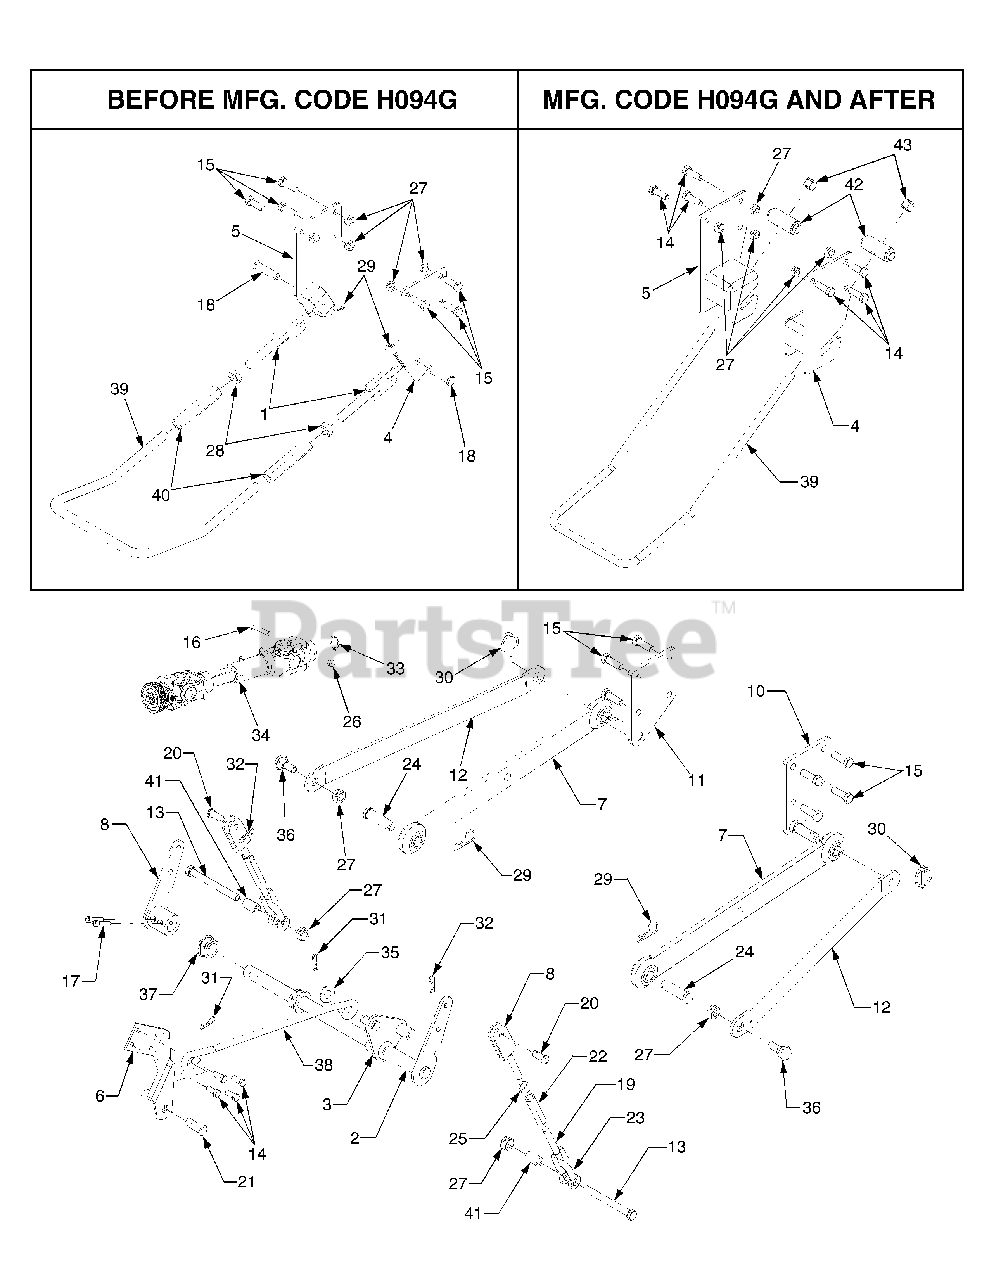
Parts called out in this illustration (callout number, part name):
1	Rod End, Deck Hanger Before Mfg. Code H094G
2	Shaft, Lift
3	Crank, Deck Lift
4	Hanger, Front RH Before Mfg. Code H094G
4	Mount, Front Hanger RH Mfg. Code H094G and After
5	Hanger, Front LH Before Mfg. Code H094G
5	Mount, Front Hanger LH Mfg. Code H094G and After
6	Lever, Deck Lift
7	Arm, Deck Lift
9	Bracket, Lift
10	Plate, Mounting RH
11	Plate, Mounting LH
14	Screw, Hex Cap, 3/8-16 x .88 GR5
15	Screw, Hex Cap, 1/2-13 x 1.50 GR5
16	Screw, Socket Hex, 5/16-18 x
17	Screw, Socket Hd. 5/16-18 x 1.50
18	Pin, Clevis, .625 x 2.4 Before Mfg. Code H094G
19	Clevis, Chain
20	Pin, Clevis, .5 x 1.18
21	Pin, Clevis
22	Shaft, Hex Check Chain
23	Clevis, Check Chain
24	Pin, Clevis, 3/4 x 2.50
25	Nut, Hex, 1/2-13 GR5
26	Nut, Hex Insert Lock, 5/16-18 .
27	Nut, Hex Lock, 1/2-23
28	Nut, Hex Jam, 3/4-10 GR5 Before Mfg. Code H094G
29	Pin, Internal Cotter (Before Mfg. Code H094G uses Qty. 4)
30	Pin, Klik
31	Pin, Internal Cotter
32	Pin, Internal Cotter
33	Ring, Retaining
34	Shaft, Drive
35	Washer, Flat, .531 x .1.25
36	Screw, Shoulder, .625 x .36: 1/2-13
37	Bearing, Flange w/Flats
38	Rod, Crank Lift
39	Rod, Deck Hanger Before Mfg. Code H094G
39	Rod, Deck Hanger Mfg. Code H094G and After
40	Turnbuckle, Hanger Rod Before Mfg. Code H094G
41	Spacer, .50 x .75 x 1.25
42	Pin, Deck Hanger Rod Mfg. Code H094G and After
43	Nut, Hex Insert Flange Lock, 5/8-11 GR5 Mfg. Code H094G and After
